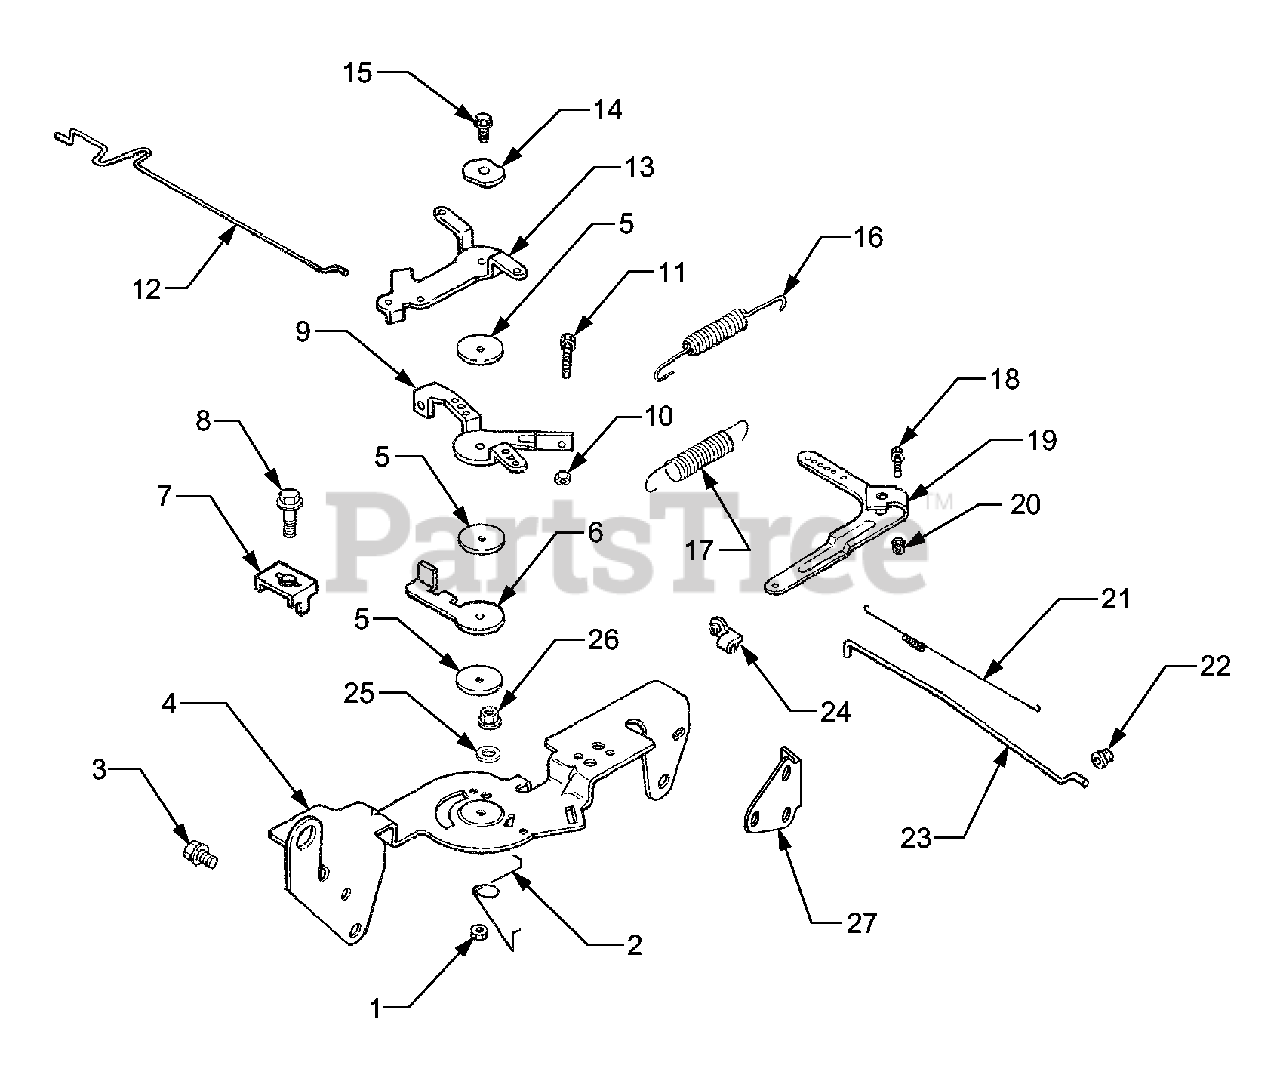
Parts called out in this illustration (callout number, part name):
1	Nut, Hex Lock M5 x 0.8
2	Spring, Choke Return
3	Screw, Hex Flange M6 x 1.0 x 16
4	Bracket, Control
5	Washer , Plain 5.5mm
6	Lever, Throttle Actuator
7	Clamp, Cable
8	Screw, Hex Flange M5 x 0.8 x 16
9	Lever, Throttle Control
10	Nut, Hex M4 x 0.7
11	Screw, Hex Cap M4 x 0.7 x30
12	Linkage, Choke
13	Lever, Choke
14	Washer, Spring 1/4"
15	Screw, Hex Flange M5 x 0,.8 x 20
16	Spring, Throttle Limiter
17	Spring, Governor
18	Screw, Round Hd. Square Neck
19	Lever, Governor
20	Nut, Hex Flange M6 x 1.0
21	Spring, Linkage
22	Bushing, Linkage Retaining
23	Linkage, Throttle
24	Bushing, Linkage Retaining
27	Bracket, Support
